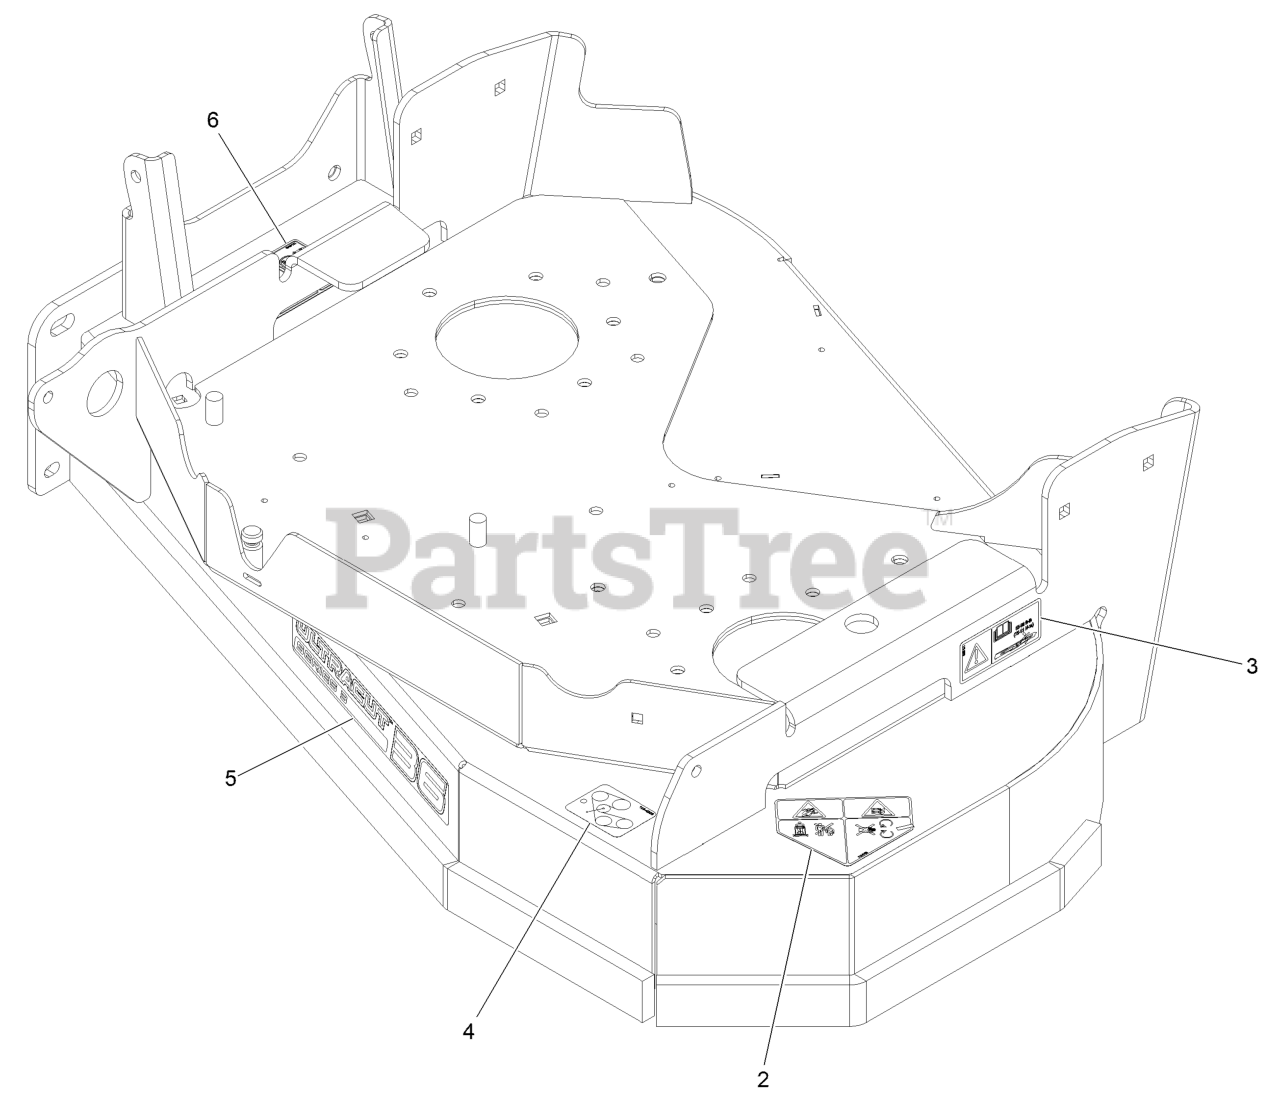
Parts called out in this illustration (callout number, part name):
2	DECAL-DANGER
3	DECAL-BOLT TORQUE
4	DECAL-BELT ROUTING 36
5	DECAL-ULTRACUT 36 SERIES
6	DECAL-DANGER
